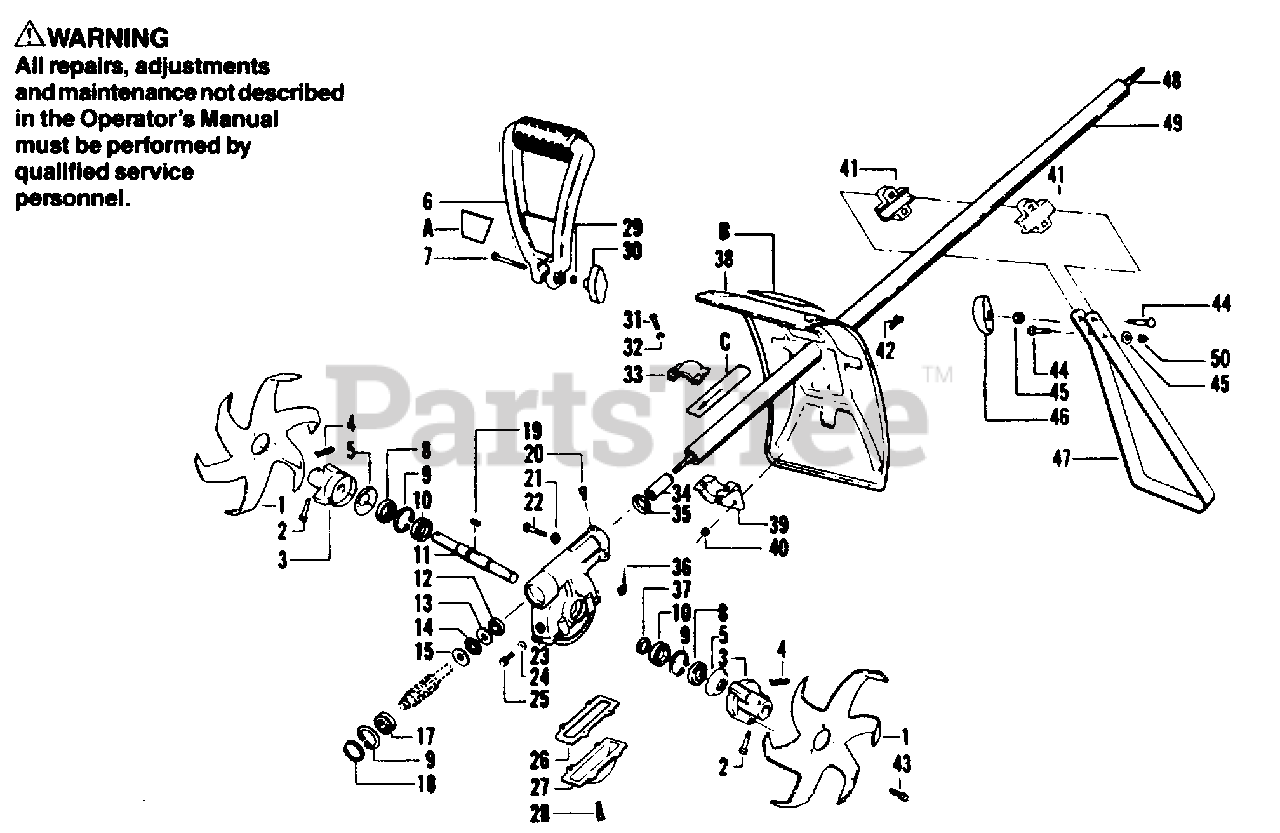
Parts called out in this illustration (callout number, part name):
2	Pin - Tine
3	HUB P142-303-7 X
4	Clip - Tine Shaft
5	Shield - Grass
6	Handle
7	Bolt - #1/4 - 20 x 1-3/4" Hex Hd. - Handle
8	Oil Seal - Tine Shaft
9	Retaining Ring
10	Bearing - Tine Shaft
11	Shaft - Tine
12	Bearing - Worm Gear - Upper
13	Thrust Collar - Worm Gear
14	Bearing - Worm Gear, Needle
15	Washer - Worm Gear
17	Bearing - Worn Gear, Lower
18	Plug - Worm Gear
19	Key - Tine Shaft
20	Bolt - Gear Housing/Shaft - 6 x 12mm
21	Washer - Gear Housing Bolt
22	Bolt - Gear Housing
23	Gear Box Ass'y (Inc.2-5, 8-28, 34-37, and Gears)
24	Washer - Grease Plug
25	Bolt - Grease Plug
26	Gasket - Gear Housing
27	Gear Housing Cover
28	Screw - Gear Housing - 5 x 14mm
29	Washer - Handle - 1/4mm
30	Knob - Handle
31	Screw - Bracket/Shaft - 5 x 14mm
32	Washer - Bracket/Shaft - 5mm
33	Upper Bracket
34	CPLG P142-115-2 X OTHE
35	Oil - Seal
36	Washer - Fiber
37	Spacer - Tine Shaft
39	Lower Bracket - 5mm
40	Nut - Bracket / Hood
41	Clamp - Drag Stake
42	Screw w/Washers - Bracket / Hood 5 x 14mm
43	Bolt with Lockwasher - Tine - 6 x 12mm
44	Bolt - Clamp -#5/16 - 18 x 2"
45	Washer - Flat - Clamp
46	Knob - Clamp
47	Drag Stake
48	Drive Shaft
49	Drive Shaft Housing Assembly
50	Nut - Jam -#5/16 - 18
A	Decal - Assist Handle
B	Decal - Hood
C	Decal - Hood Location (Not a serviceable part)
